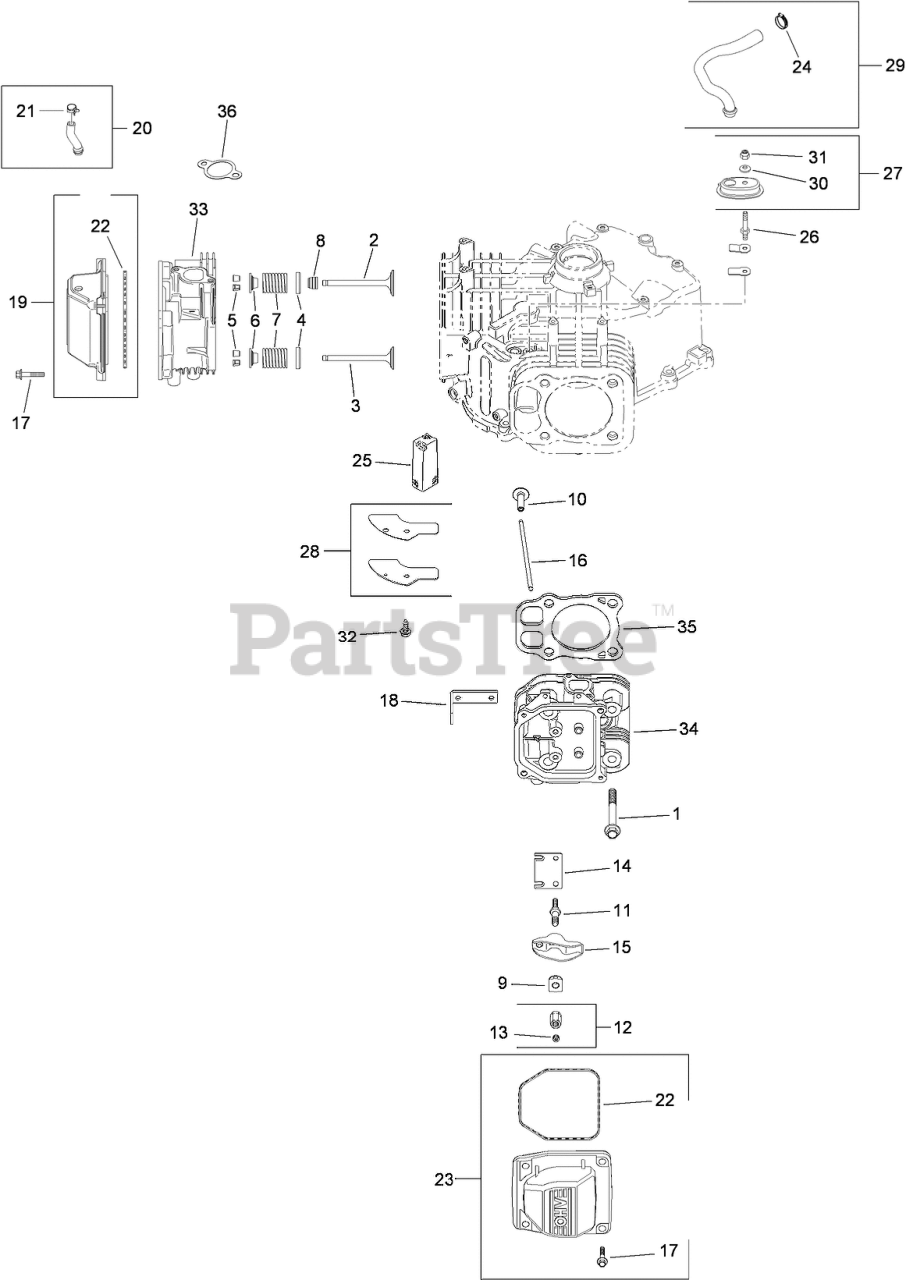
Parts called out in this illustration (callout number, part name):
1	SCREW-FLANGE (M10X1.5X90)
2	VALVE-INTAKE (STD)
3	VALVE-EXHAUST (STD)
4	RETAINER-SPRING
5	RETAINER KIT
6	CAP-SPRING, VALVE
7	SPRING-VALVE
8	SEAL-STEM, VALVE
9	PIVOT-ARM, ROCKER
10	TAPPET KIT
11	STUD-ROCKER
12	HEX NUT ASM (INCLUDES REF 13)
13	SCREW-SET
14	PLATE-GUIDE
15	ARM-ROCKER
16	ROD-PUSH
17	SCREW-FLANGE (M6X1.0X30)
18	STRAP-LIFTING
19	BREATHER VALVE COVER KIT (INCLUDES REF 22 QTY 1])
20	FUEL PUMP HOSE W/CLAMP KIT (INCLUDES REF 21)
21	CLAMP-HOSE
22	O-RING
23	PLAIN ROCKER COVER KIT (INCLUDES REF 17 QTY 1], 22)
24	CLAMP-HOSE, SPRING (1/2)
25	FILTER-BREATHER
26	STUD-COVER, BREATHER
27	BREATHER HOUSING KIT (INCLUDES REF 30, 31)
28	BREATHER COVER KIT
29	BREATHER HOSE KIT (INCLUDES REF 24)
30	WASHER-SEALING
31	NUT-LOCK (M5X.8)
32	SCREW-FLANGE, THREAD FORMING (M6X1.0X16)
33	CYLINDER HEAD NO.1 ASM (INCLUDES EXHAUST MOUNTING HARDWARE)
34	CYLINDER HEAD NO.2 ASM (INCLUDES EXHAUST MOUNTING HARDWARE)
35	CYLINDER HEAD GASKET KIT
36	GASKET-EXHAUST
